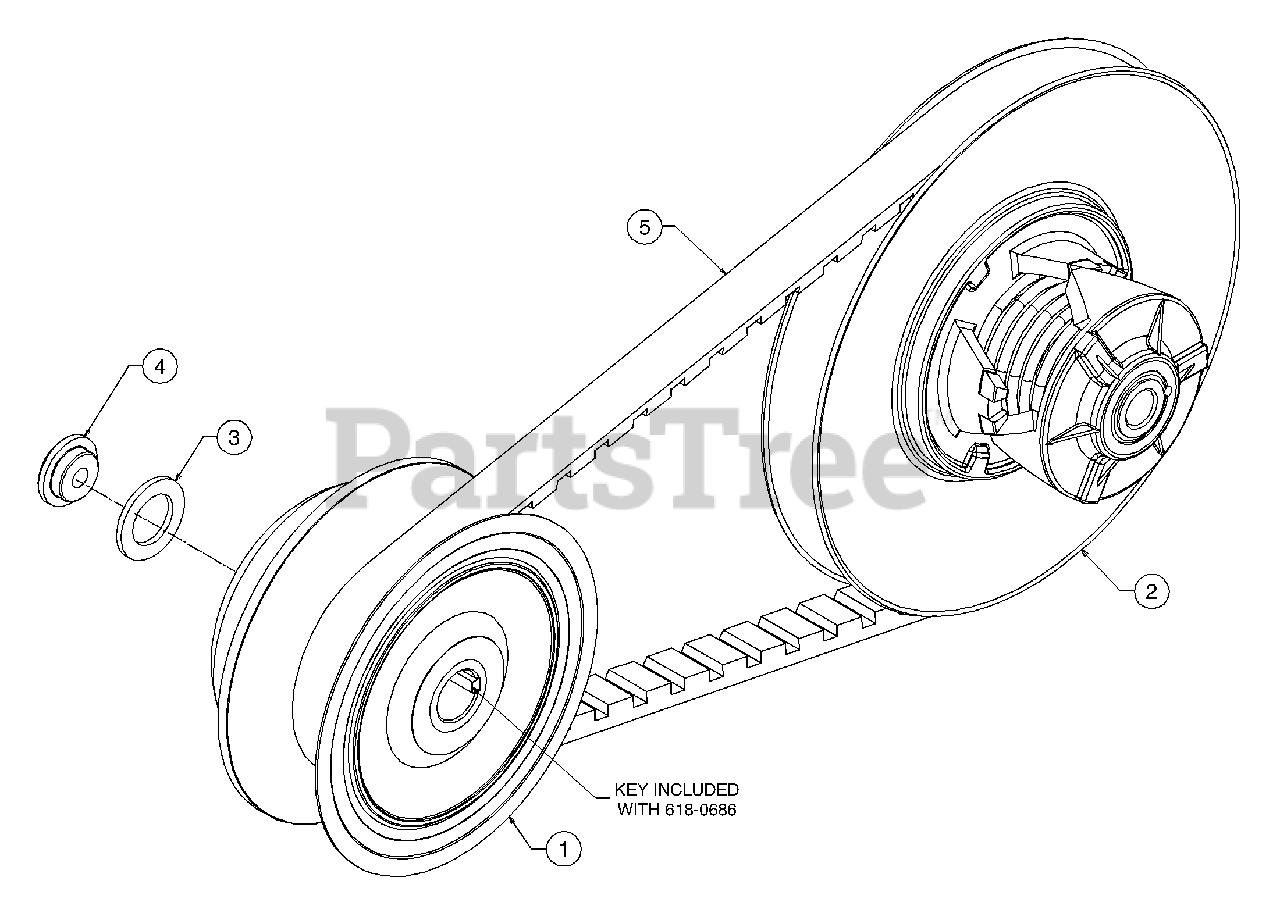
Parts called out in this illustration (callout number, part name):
1	Clutch Assembly, Engine
2	Clutch Assembly, Transmission
3	Washer, 1.03 x 1.625 x .12
4	Spacer, Drive, .39 ID x 1.00 OD
5	V-type Belt, Cogged, 1.19
